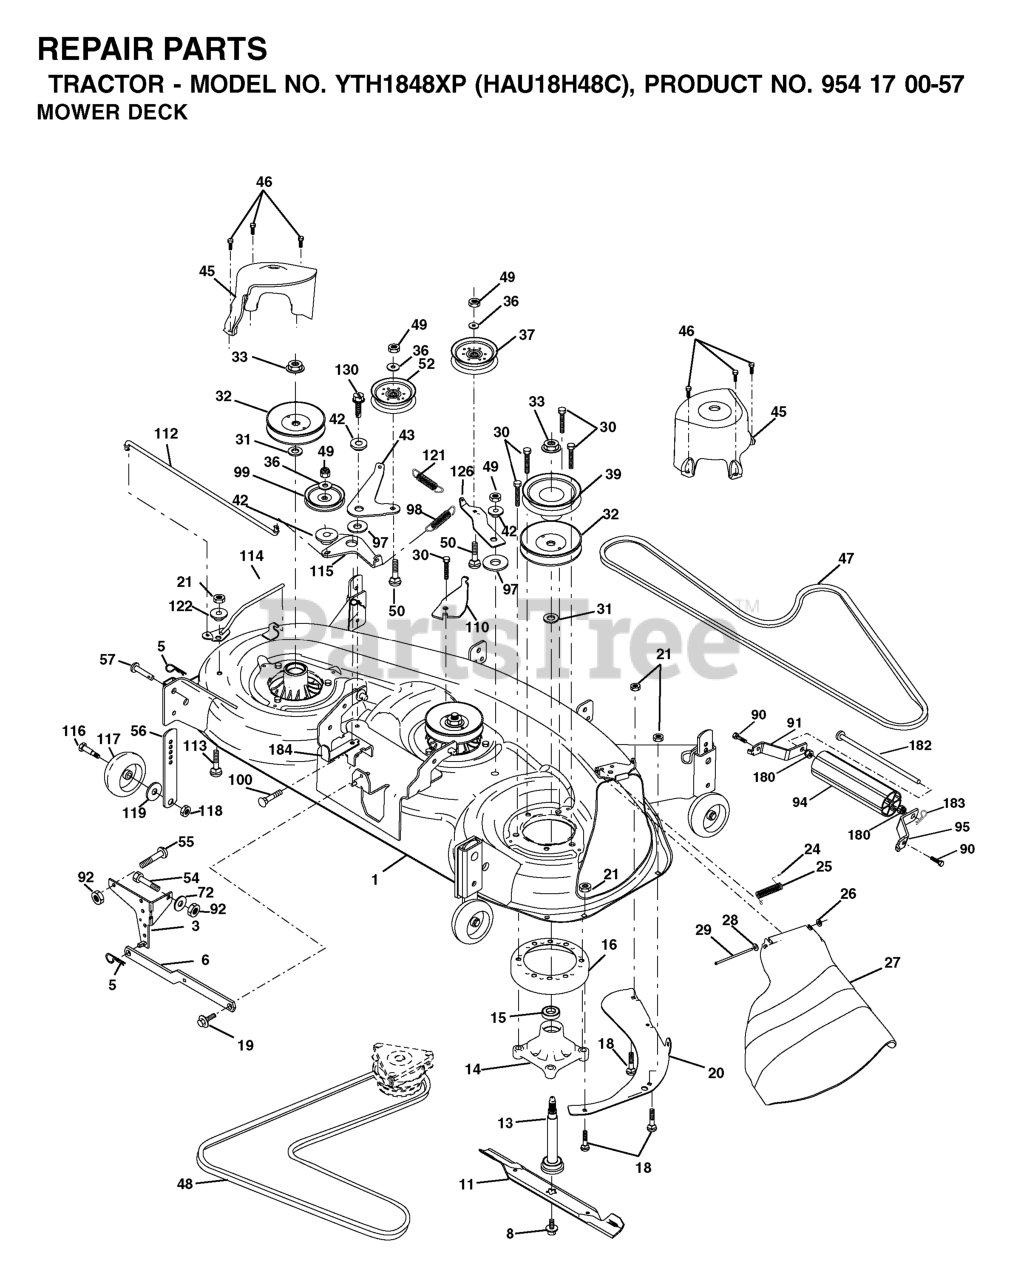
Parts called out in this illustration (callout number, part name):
1	DECK WELDMENT MOWER, 48
3	BRKT ASM SWAY BAR
5	RETAINER-SPRNG RB
6	BAR SWAY DECK
8	BOLT 7/16 ASM BLADE
11	48" HI-LIFT BLADE
13	SHAFT ASM W/LOWER BEARING
14	HOUSING, MANDREL 48"
16	STRIPPER.MANDREL.ROUND.BLACK
17	BOLT
18	BOLT
19	BOLT SHD 5/16-18
20	BAFFLE, VORTEX MWR
21	LOCKNUT
24	CAP-SLEEVE LT
25	SPRING, TORSION
26	NUT PUSH M
27	DEFLECTOR SUBS TO 532 180655
28	Washer 11/32 x 5/8 x 16 Ga SD
29	ROD.HINGE
30	SCREW, WASHER HEAD
31	WASHER
32	PULLEY, MANDREL
33	NUT, FLG TOPLOCK 9/16"
36	WASHER
37	PULLEY.IDLER.FLAT
39	PULLEY.DRIVEN.DECK.48'
42	SPACER RETAINER
43	ARM, IDLER SECONDARY
45	COVER, MANDREL DECK
46	SCREW.1/4-20X5/8
47	V-BELT, 48"SECONDARY
48	V-BELT PRIMARY 48"
50	BOLT.3/8-16X1.50
52	PULLEY.IDLER.FLAT.46.PR.DR.
55	BOLT D
56	BAR.ADJUST.WHEEL.ANTI.SCALP.BL
57	RIVET.PIN.HEAD.YELLOW.
72	WASHER
90	BOLT RB
91	BRKT.NOSEROLLER.LH.48"
92	NUT
94	NOSE ROLLER 48"
95	BRKT.NOSEROLLER.RH.48"
97	HARDENED WASHER
98	SPRING PRIMARY DRIVE
99	PULLEY,IDLER"V"
110	ARM, SPRING SECONDARY
112	LEVER, TENSION RELIEF LINK
114	LEVER ASM, TENSION RELIEF
115	ARM, SPRING TENSION RELIEF
116	BOLT, SHOULDER
117	WHEEL GAGE DONUT
118	LOCKNUT
119	WASHER.5/16.FLAT.STE.STD.
121	SPRING.DRIVE.SECONDARY.48".DEC
122	BUSHING, PIVOT TENSION RELIEF
126	ARM, IDLER PRIMARY DECK
130	SCREW 3/8-16X1
180	NUT.71038.31-18.HEX.NYLOCK
182	ROD.ROLLER.NOSE.NARROW.48"
183	SPRING RETAINER
184	KEEPER BELT IDLER PLATED
